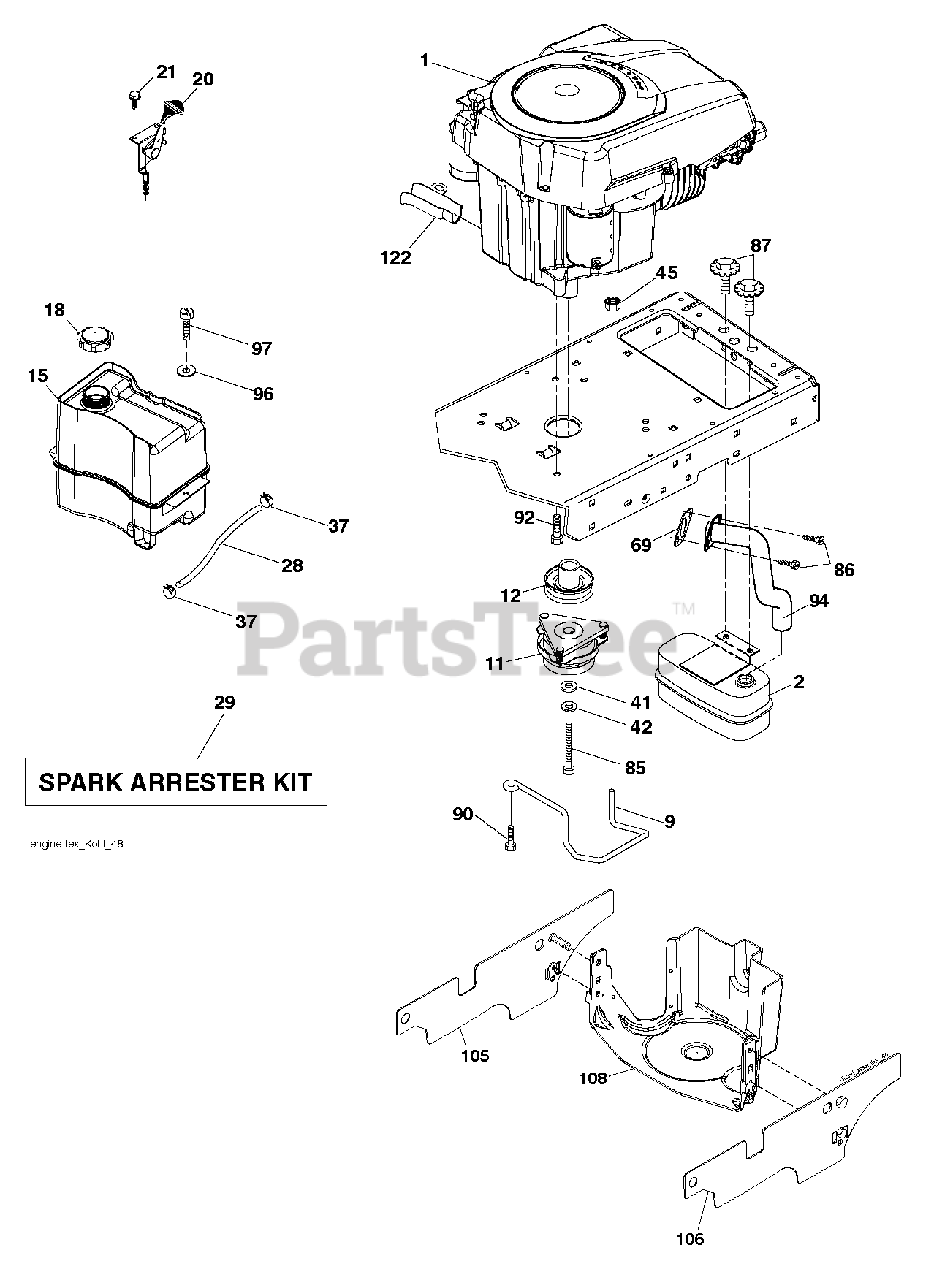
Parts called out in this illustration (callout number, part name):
2	MUFFLER.SINGLE.CYL.KOHL/B&S
9	KEEPER.BELT.ENGINE.4.2
11	RB.CLUTCH.OGURA.4.4.PD
12	PULLY ENGINE
15	RP TANK FUEL FRT 1.5 GAL
18	CAP ASM.FUEL.2.25"FR.
20	CONTROL.TH/CK.C.
21	SCREW.#10 X 0.750.BOS
28	LINE.FUEL.20
29	KIT.SPARK ARRESTOR 794945 B&S
37	HOSE CLAMP
42	LOCKWASHER
45	NUT
69	GASKET.EXHAUST.KOHLER
85	BOLT HEX 7/16-20X4-1/4"
86	SCREW.SOCKET HD.5/16-1
87	BOLT, 5/16-18 X 1 3/4
90	SCREW 3/8-16X1
92	SCREW 3/8-16X1
94	RP.TUBE.EXHAUST.KOHL.COURAGE
97	SCREW HEXWSHR 1/4-20X3/4
108	ENGINE COVER
122	EXTENSION DRAIN OIL
